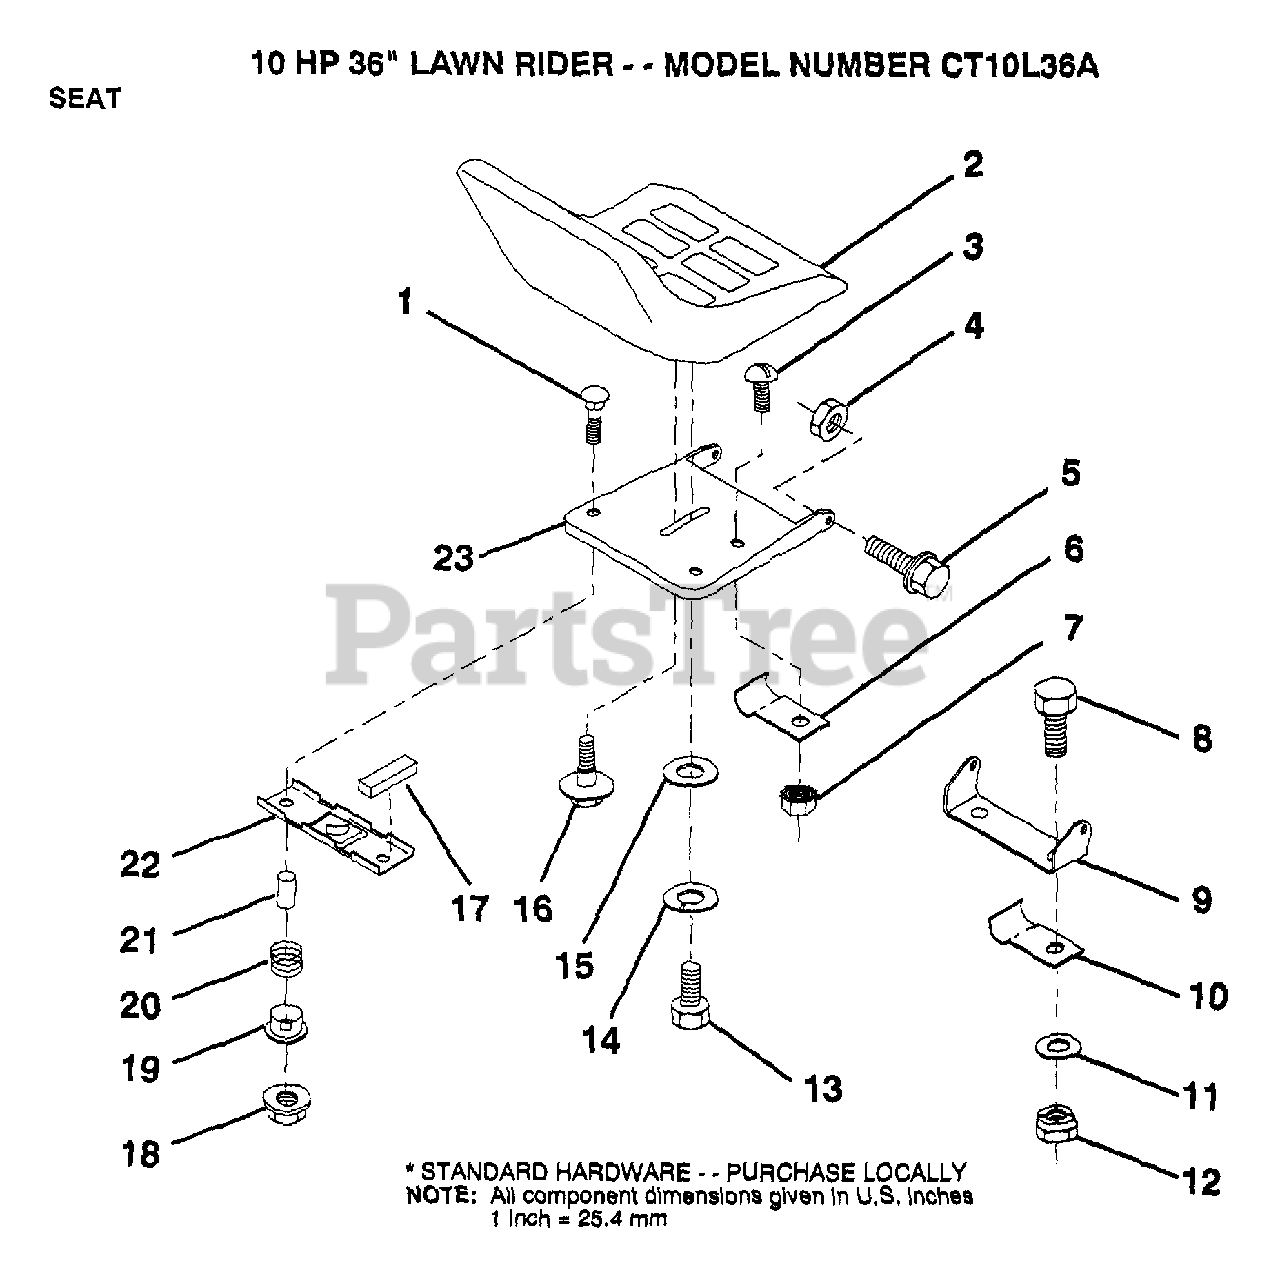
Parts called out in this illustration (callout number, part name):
7	"NUT,KEPS"
10	"CLIP,INSULATOR"
11	WASHER
13	BOLT
14	LOCKWASHER
15	WASHER
16	"BOLT,SHOULDER"
17	STRIP FORM
19	BUSHING
20	SPRING
21	SPACER SPLIT
22	BRKT SWITCH
